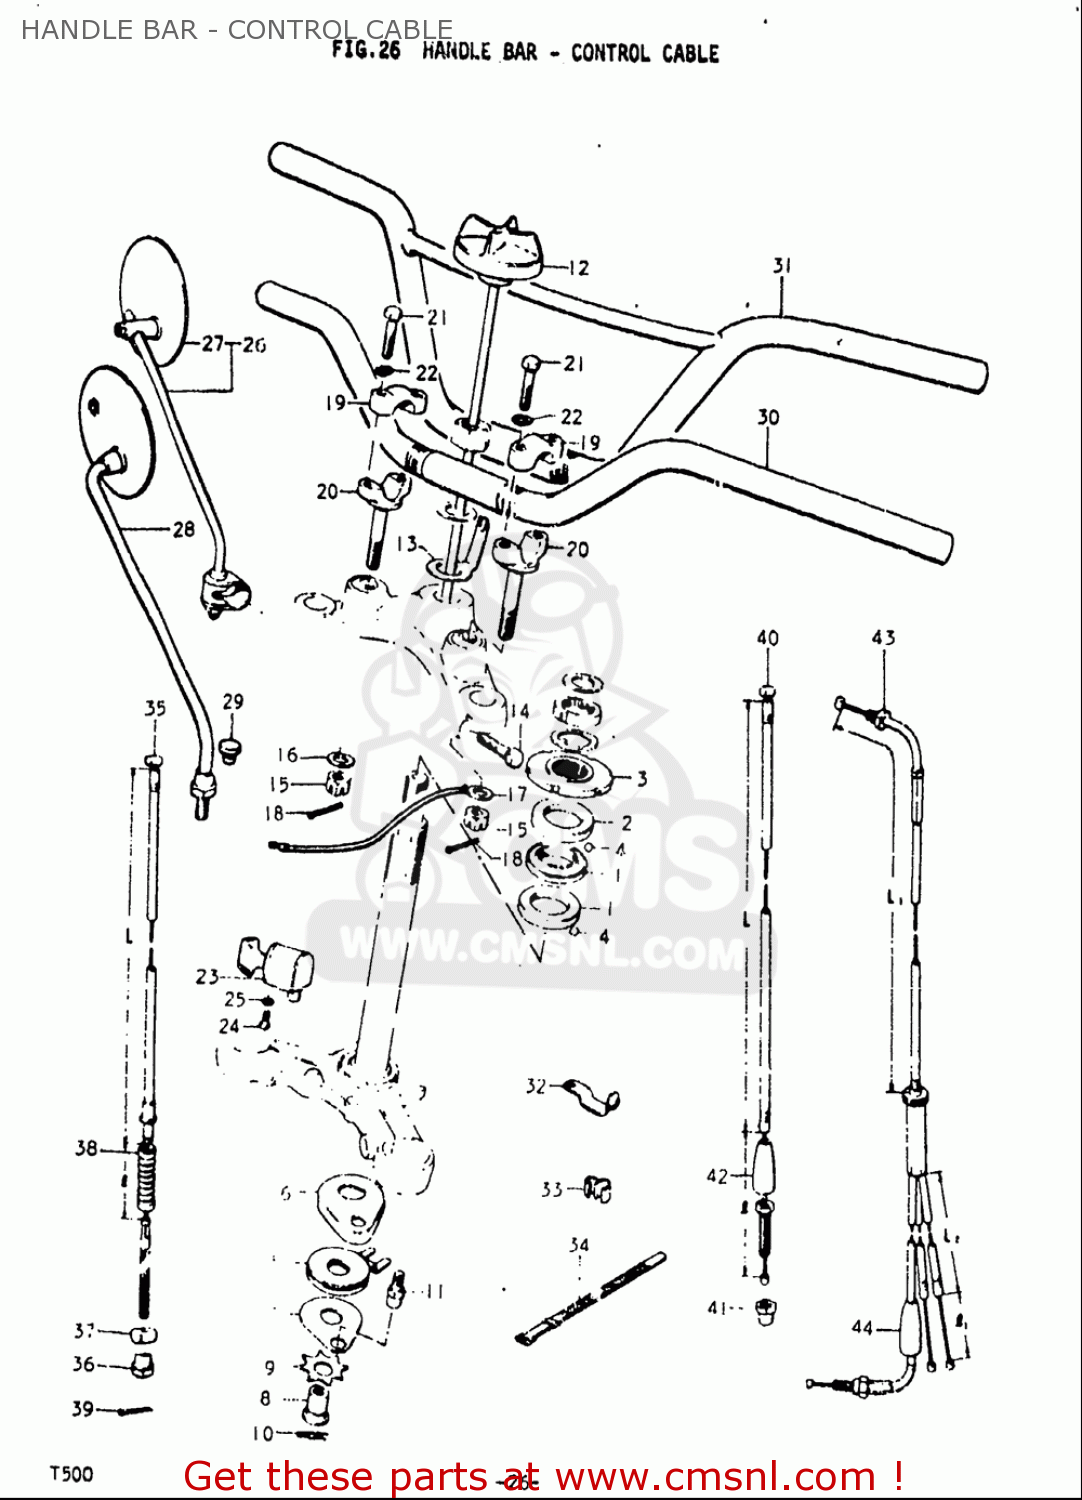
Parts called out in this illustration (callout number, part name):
1	LACE,STEERING INNER LWR
3	NUT,STEERING STEM
4	BALL
7	SPACER,STEERING DAMPER
8	HUB,HANDLEBAR DAMPER S
9	SPRING, DAMPER ADJUST
11	BRACKET,STEERING DAMPER
13	STOPPER, DAMPER KNOB
14	BOLT
15	NUT
16	WASHER(10.5X28X2.3)
18	COTTER PIN
19	HOLDER,HANDLEBAR
21	BOLT
22	WASHER,LOCK
25	WASHER,LOCK
28	MIRROR ASSEMBLY,LEFT
29	CAP(OD:14)
30	HANDLEBAR
33	CLIP
34	CLAMP
35	CABLE ASSY,BRAKE
36	NUT
37	PIN(13X18)
38	SEAL,DUST
39	PIN
40	CABLE,CLUTCH
41	NUT
43	CABLE ASSY,THROTTLE
44	SEAL,DUST(7X18X30)
